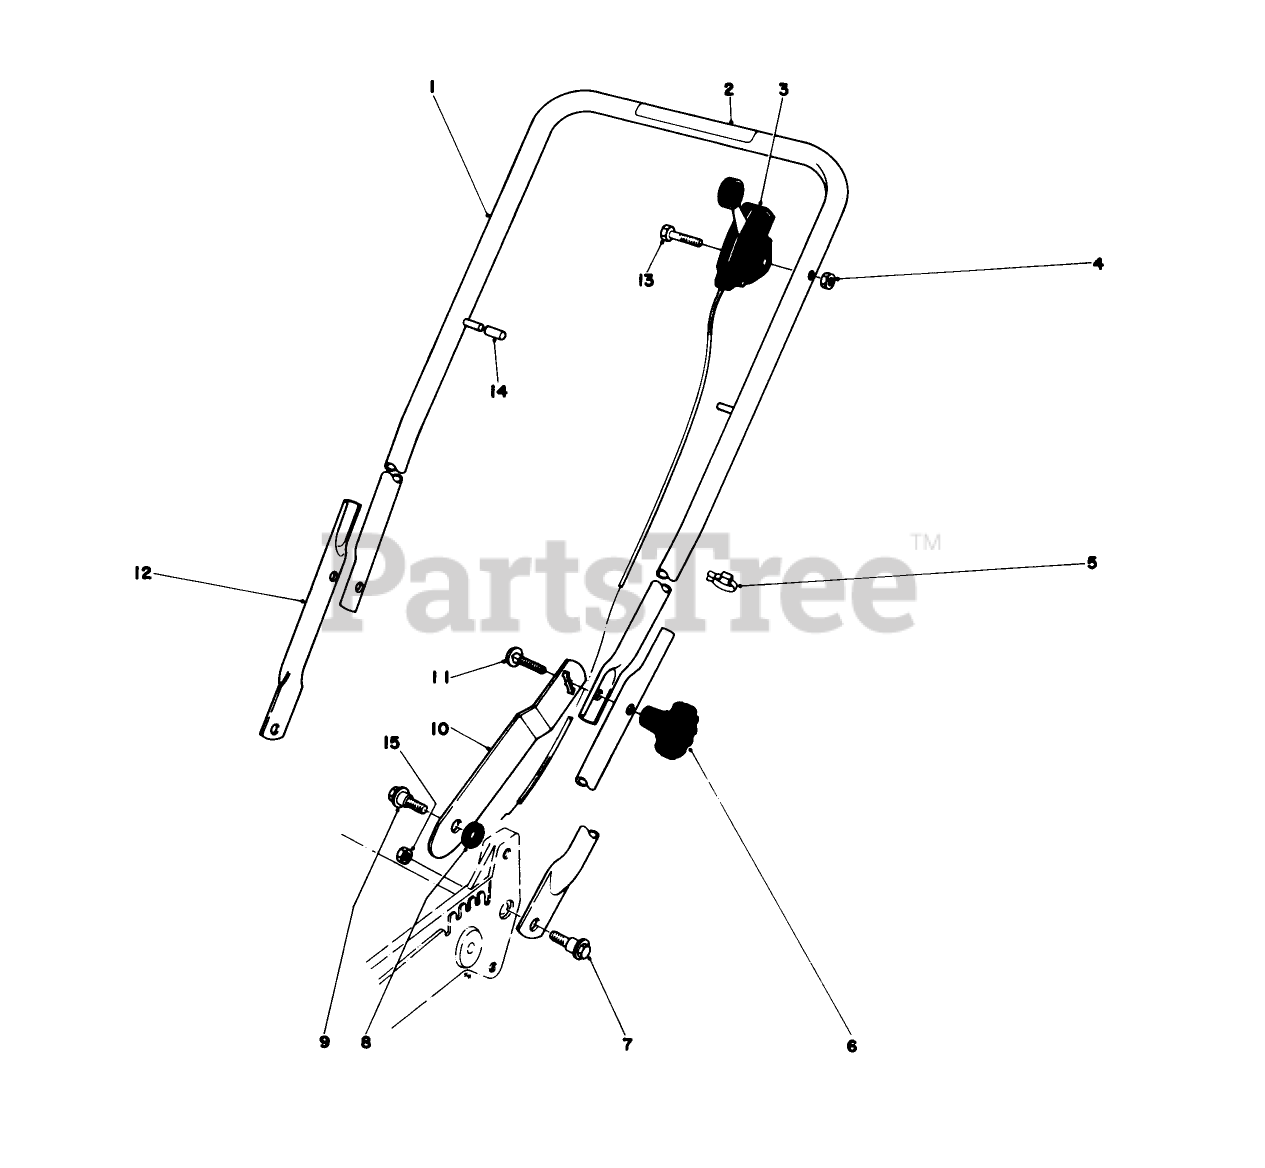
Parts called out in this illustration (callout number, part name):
5	BOWDEN CLIP
7	SCREW-SHOULDER
8	SPACER
9	SCREW-SHOULDER
11	BOLT-CAR
13	SCREW-HH
14	Cap Vinyl
